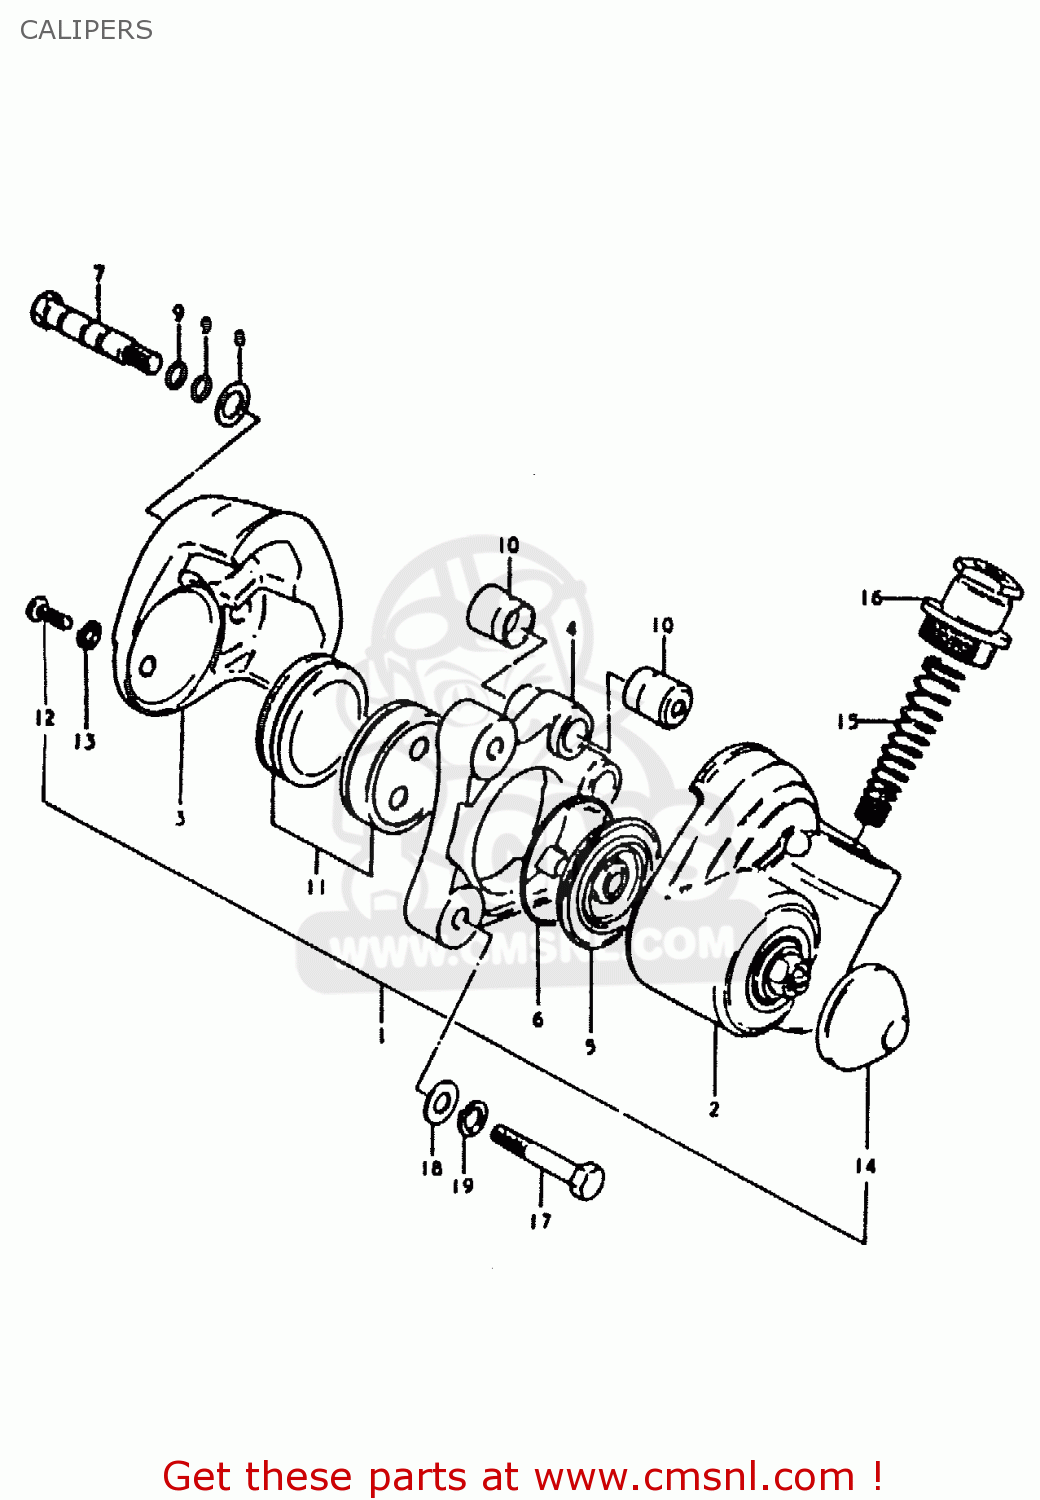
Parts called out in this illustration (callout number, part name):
1	CALIPERS ASSY
2	HOUSING, CALIPAS NO.1
3	HOUSING, CALIPAS NO.2
4	HOLDER, CALIPAS
5	BOOT
6	CLIP
7	AXLE
8	WASHER
9	O RING,CALIPER AXLE
10	COVER,AXLE DUST
11	PAD SET,BRAKE (MCA)
12	SCREW
13	LOCK WASHER
14	BOOT
15	SPRING, LEVER RETURN
16	PLUG
17	BOLT
18	WASHER
19	WASHER,LOCK,8.
